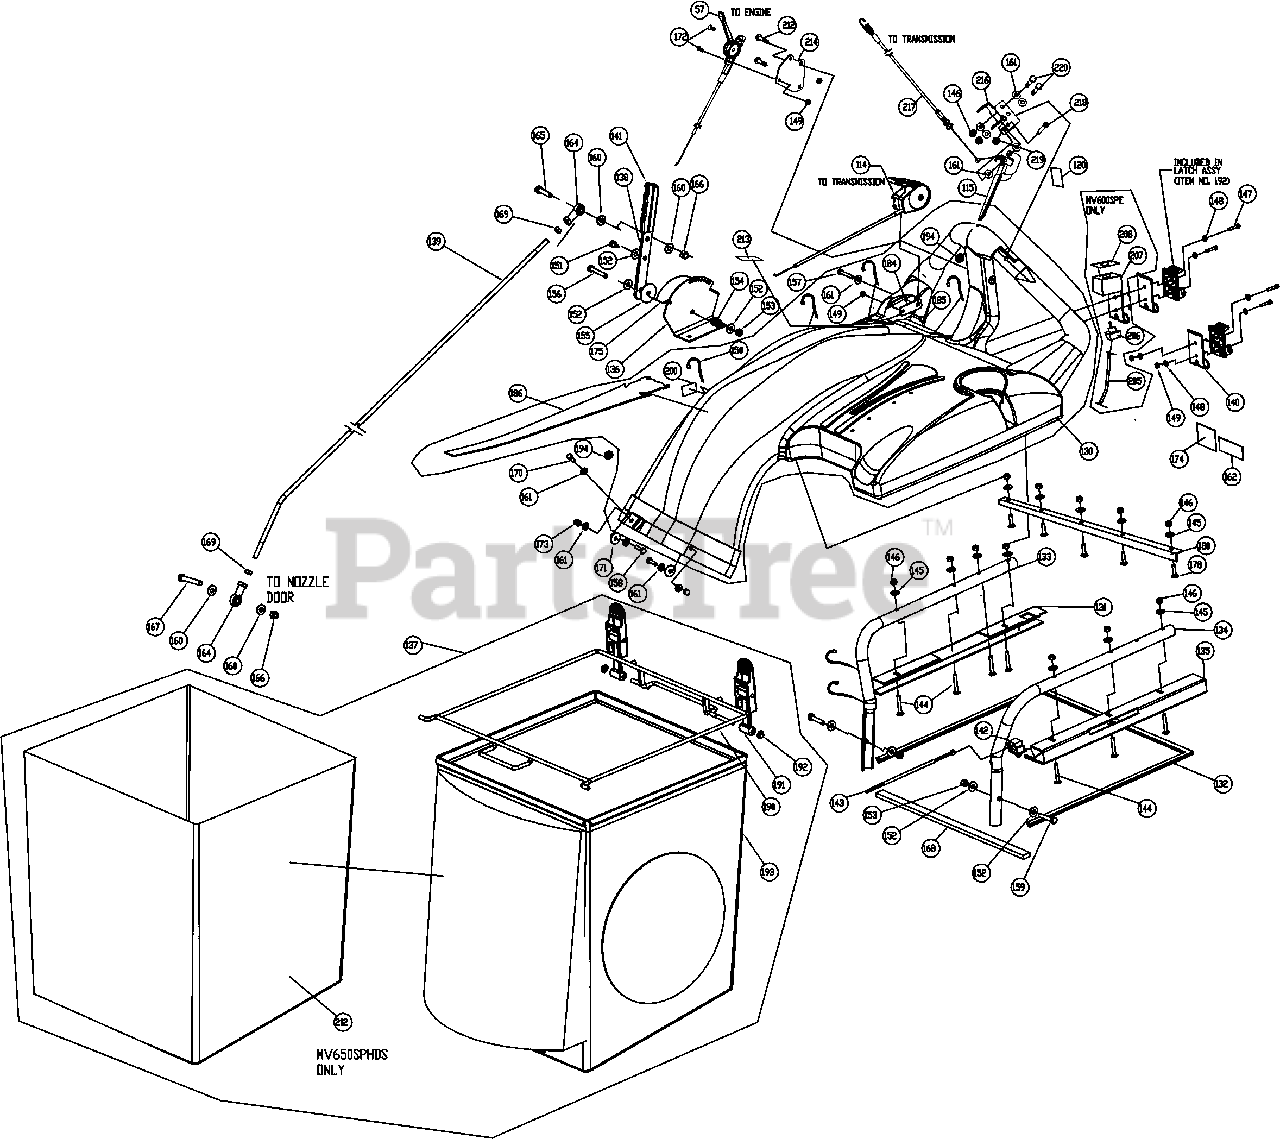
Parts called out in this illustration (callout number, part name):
57	CONTROL THROTTLE
114	CONTROL SHIFT WESCON MV VAC
115	HANDLE MV CLUTCH CABLE
120	LABEL CLUTCH DRIVE
130	HOOD ASSY W/ LABEL MV VAC
131	BRACKET BAG CHANNEL RH W/SEAL MV VAC
132	SEAL BAG MV VAC
133	TUBE HANDLE BRACE RH MV VAC
134	TUBE HANDLE BRACE LH MV VAC
135	BRACKET BAG CHANNEL LH
136	BRACKET NOZZLE DOOR ADJ W/LABEL MV VAC
137	BAG ASSEMBLY MV VAC
138	BAR LIFT NOZZLE DOOR W/ GRIP MV VAC
139	ROD LIFT NOZZLE DOOR SP VAC
140	PLATE BAG LATCH MV VAC
141	GRIP LEVER LIFT
142	SWITCH INTERLOCK VAC
143	WIRING HARNESS ELEC START MV
144	BOLT CARRIAGE 1/4-20 X 1.75
145	WASHER 1/4" FC ZP
146	NYLON INSERT LOCKNUT 1/4-20 UNC
147	SCREW HEX HEAD #10-24 X 1"
148	WASHER #10 SAE ZP
149	NYLON INSERT LOCKNUT 10-24 UNC
151	PIN SCREW 1/4-28
152	WASHER 5/16 FLATWASHER Z/P
153	NYLON INSERT LOCKNUT 5/16-18 UNC
154	SPRING LEVER GZ
155	FIBRE WASHER
156	SCREWCAP 1/4-20X2"
157	SCREWCAP 1/4"-20X2 1/4" ZP
158	SCREWCAP 1/4-20X1" ZP
159	SCREWCAP 5/16-18 X 1.75 ZP
160	WASHER 3/8 FC
161	WASHER 1/4" SAE ZP
162	LABEL SAFETY PROTECT READ MANUAL
164	ROD END BALL JOINT 3/8 NF
165	SCREW CAP 3/8-16X1 1/2 ZP
166	NYLON INSERT LOCKNUT 3/8-16 UNC
167	SCREWCAP 3/8"-16X2 1/2" ZP
168	SEAL BAG FRONT HOOD 20.5 LONG
169	NUT REG 3/8-24 NF
170	SCREWCAP 1/4"-20X3/4" HCS ZP
171	WASHER FENDER 1/4 ZP
172	SCREW MACH FLAT HD PHIL #10-24 HEX
173	NUT ACORN 1/4-20
174	LABEL DANGER FLYING DEBRIS
175	LABEL NOZZLE DOOR MV VAC
178	BOLT CARRIAGE 1/4-20 X 3/4"
180	BRACKET HOOD FRONT STRAIGHTENER
184	PLATE SHIFT CONTROL ANTI ROT
185	SCREWCAP #10-24X1 1/4"
186	LABEL HOOD DECAL
190	ROD BAG WA MV VAC
191	LATCH RUBBER ASSEMBLY MV VAC
192	PAL NUT 0.312
193	BAG DEBRIS MV VAC
194	GROMMET RUBBER 5/8" OD X 3/8" ID
200	LABEL MADE IN U.S.A.
205	CABLE HARNESS ELECT START
207	BRACKET START SWITCH MV VAC
208	LABEL START STOP EN/SP
213	LABEL THROTTLE BC
214	PLATE MV THROTTLE CONTROL
215	CABLE THROTTLE CONTROL 72"
216	BRACKET MV CABLE MOUNT WA
217	CABLE DRIVE MV CLUTCH
218	BOLT SHOULDER 1/4" X 1 3/4"
219	NUT LOCK #10-24 HEX
220	SCREWCAP 1/4-20 1 3/4 HCS ZP
221	SCREW PLASTITE 1/4"-10 X 3/4" HWH ZP
